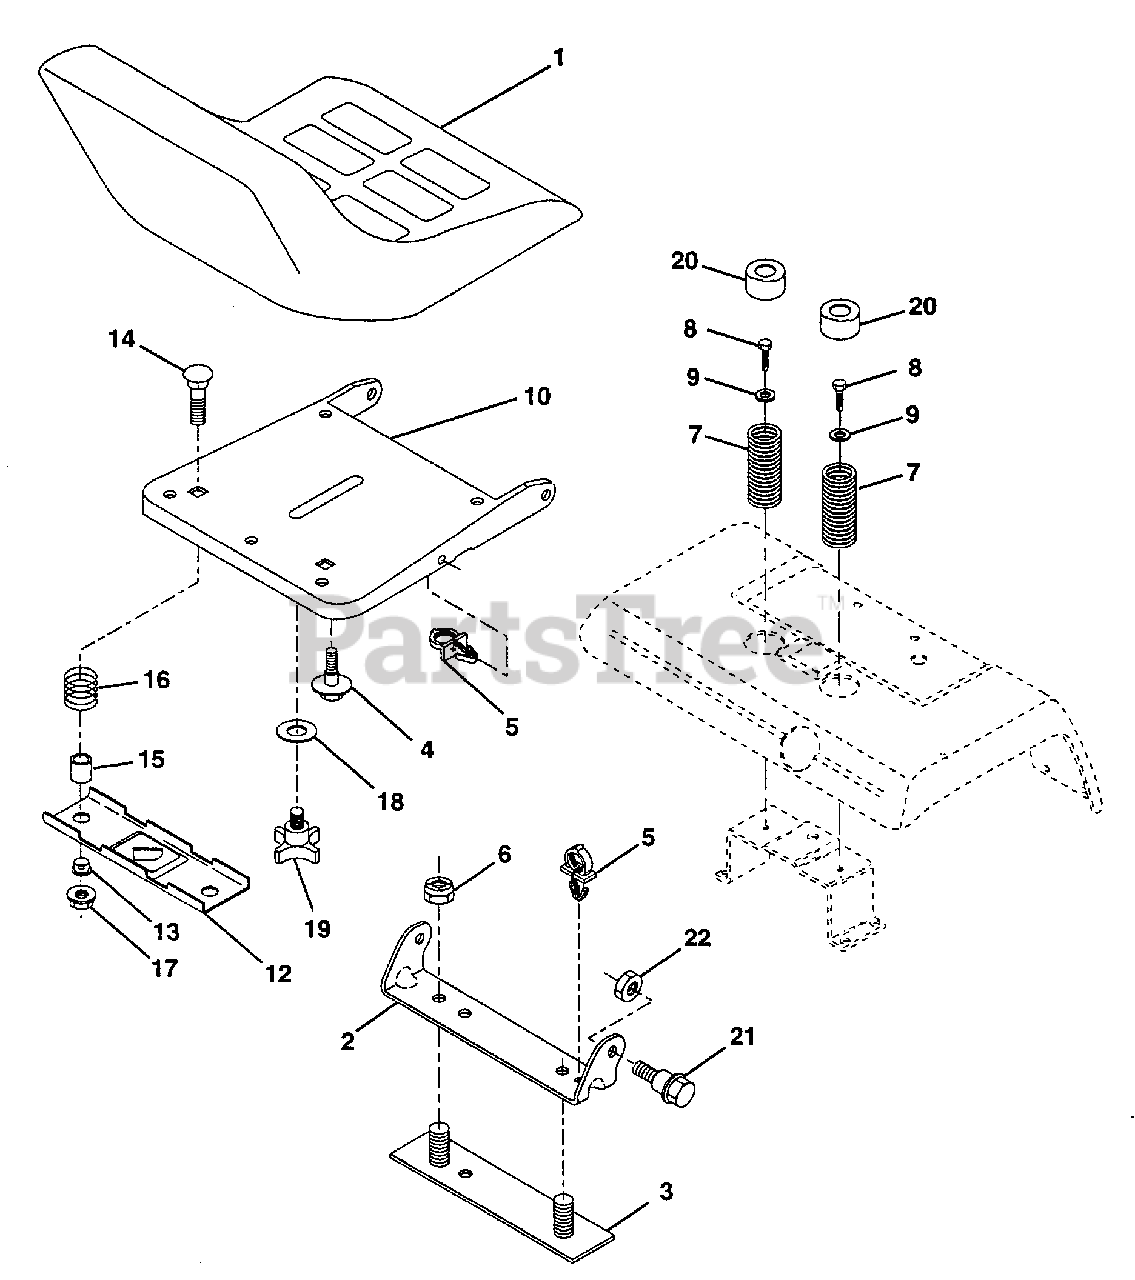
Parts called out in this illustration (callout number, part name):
2	BRACKET PVT SEAT
3	STRAP ASM FENDER
4	"BOLT,SHOULDER"
5	CLIP.PUSH-IN.HING
7	SPRING COMPRESSIO
8	SCREW LT
9	WASHER
12	BRKT SWITCH
13	BUSHING
15	SPACER SPLIT
16	SPRING COMPRESSED
18	WASHER
19	"KNOB 1/2"" YT"
20	CAP SPRING
21	BOLT.SHLD.5/16-18
